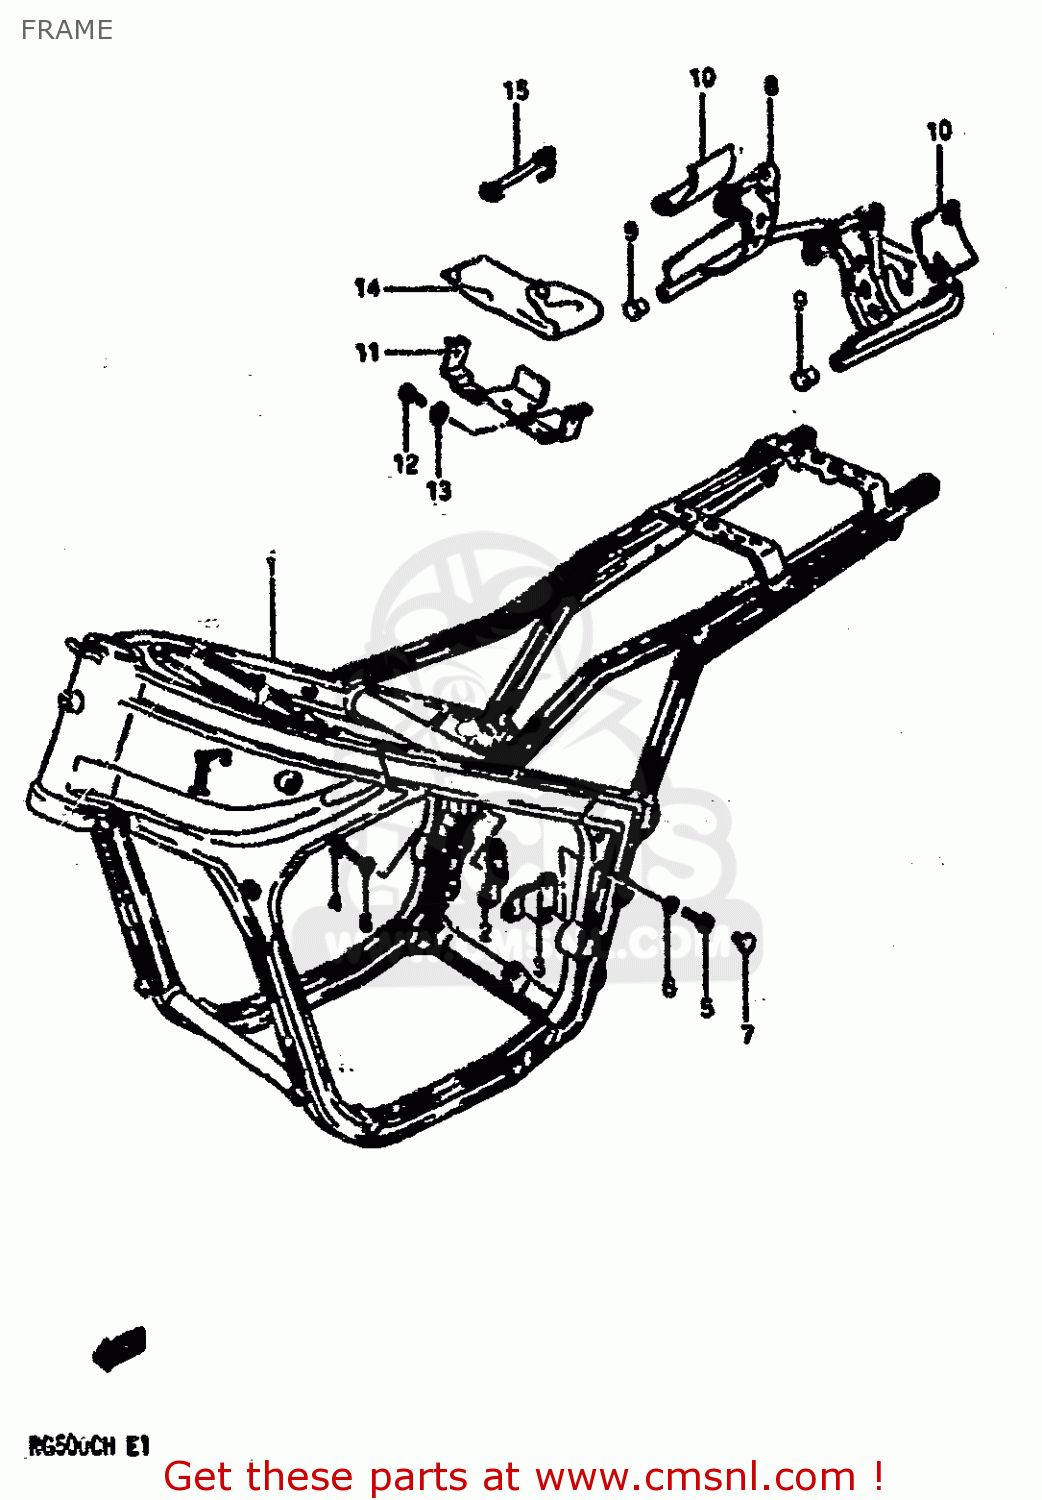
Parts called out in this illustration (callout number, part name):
1	FRAME
2	PLATE,ENGINE MOUNT RH
3	PLATE,ENGINE MOUNT LH
4	BOLT,RH
5	BOLT, FRONT RH
6	WASHER
7	CAP,ENGINE MOUNTING
8	GRIP,REAR
9	PLUG
10	HEAT SHIELD,FRAME COVER
11	HOLDER,TOOL
12	BOLT
13	WASHER (6.5X18X1.6)
14	TOOL ASSY
15	BAND,TOOL
